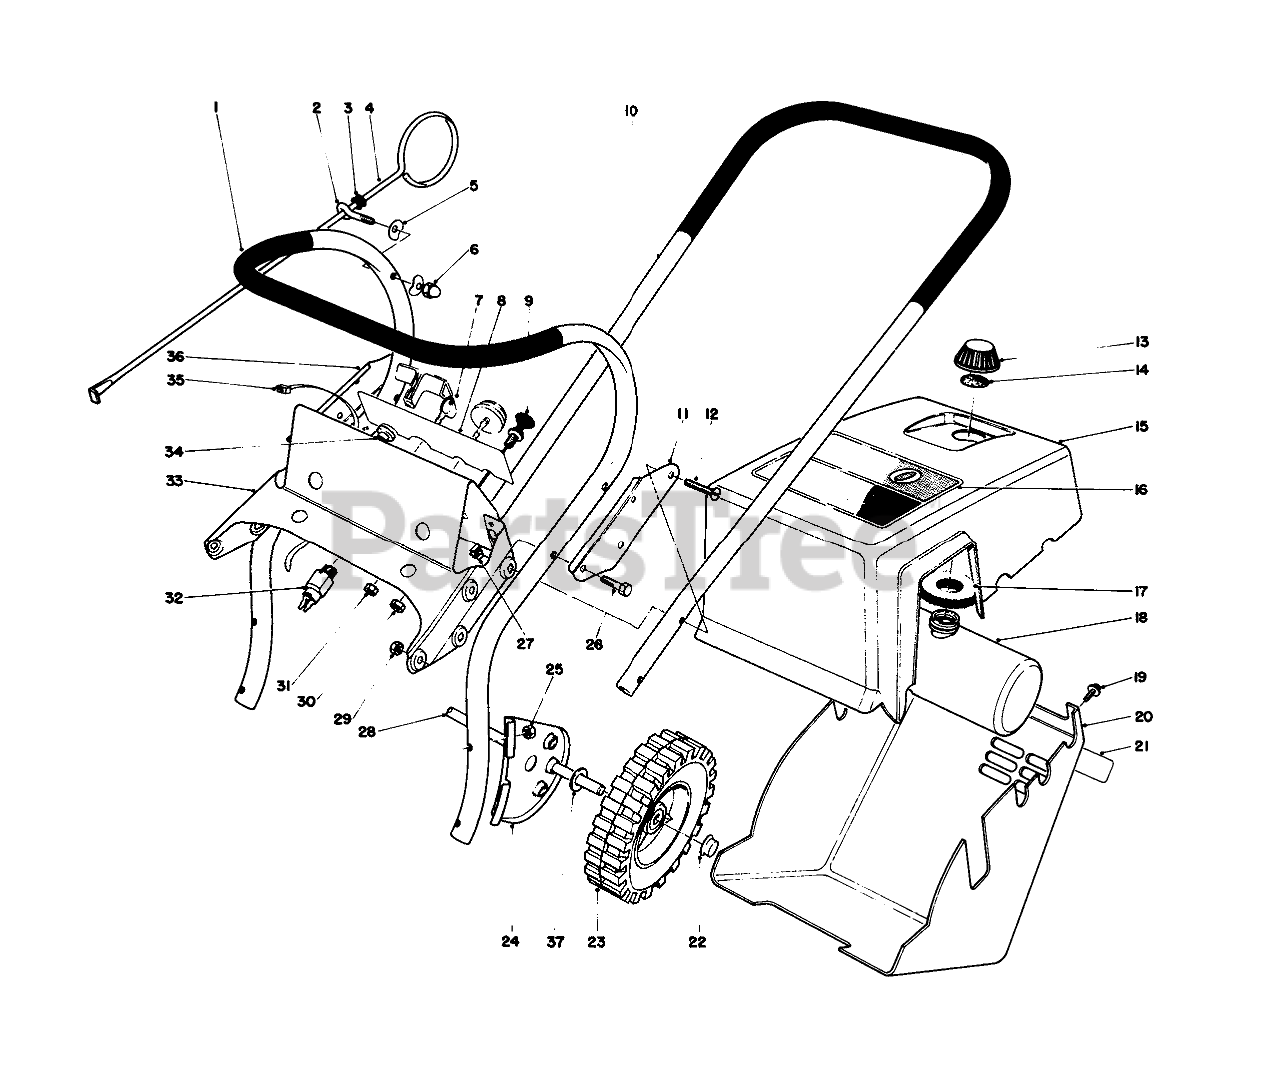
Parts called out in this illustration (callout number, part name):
1	LOWER HANDLE
2	Bolt-Eye
3	GROMMET
4	Vane Adj. Rod
5	WASHER
6	NUT-CAP
7	Key
8	CONTROL PANEL DECAL
9	CHOKE CONTROL
10	Upper Handle
11	SPLICE PLATE
12	Sems Mach. Screw
13	Gas Cap Assy. (Incl. Ref. #14)
14	GAS CAP GASKET
15	Shroud (Incl. Ref. #16)
16	Decal-Toro
17	FOAM PAD
18	Gas Tank Assembly (Incl. Ref. #13 & 14)
19	SCREW
20	Lower Shroud (Incl. Ref. #21)
21	Decal-Instruction
22	RETAINER-PUSH ON
23	WHEEL
24	Wheel Bracket
25	NUT-HEX
26	SCREW-HH
27	Nut Retainer
29	NUT-LOCK, CONE
30	PAL NUT/CHOKE CNTRL
31	NUT-KEPS
32	SWITCH-ON / OFF
33	Tank Support & Control Panel (Incl. Ref. #8)
34	GUIDE-ROPE, STARTER
35	Strap
36	Plate-Splice
37	WASHER-FLAT
